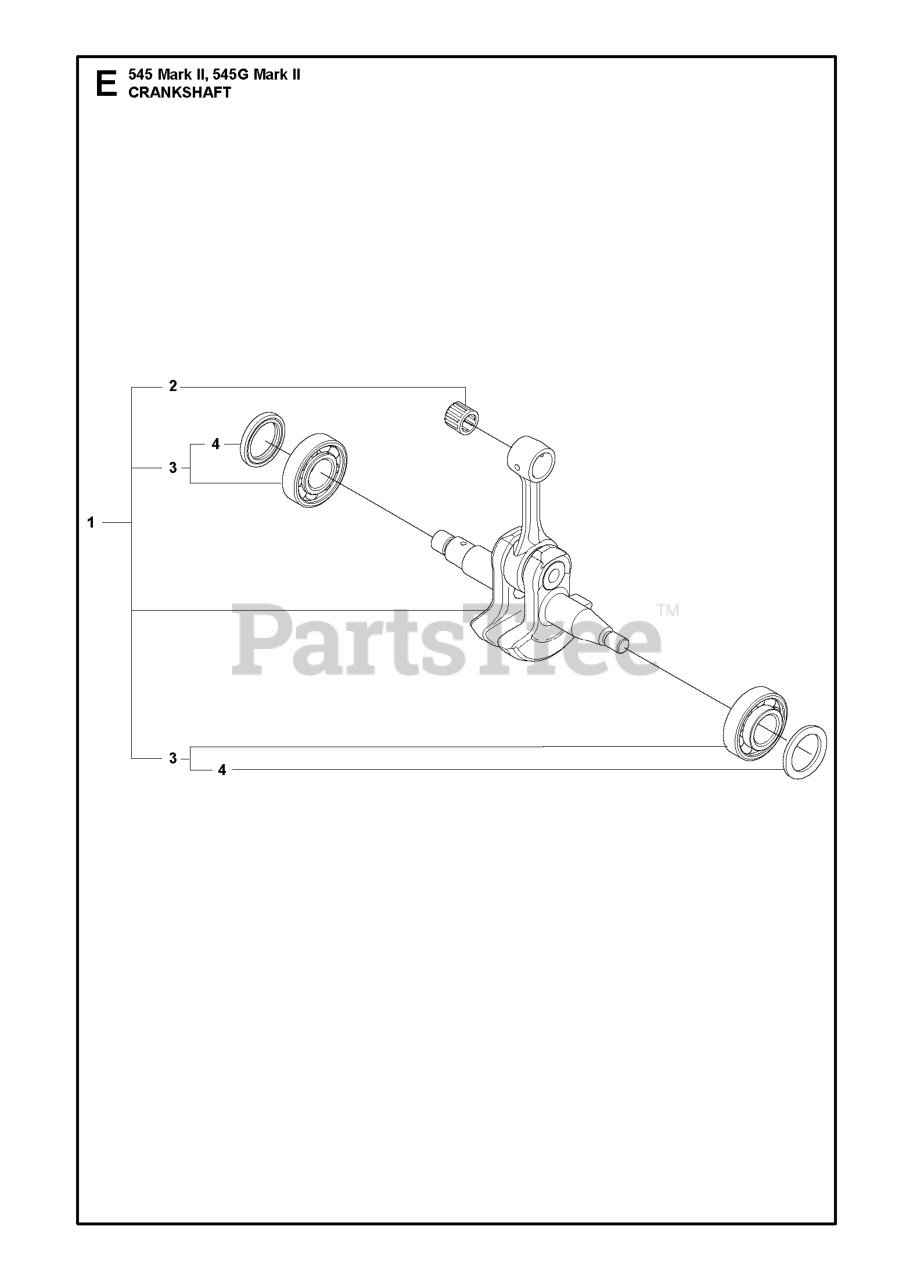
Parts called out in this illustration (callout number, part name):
1	CRANKSHAFTS
2	NEEDLE BEARING
4	RADIAL SEAL
